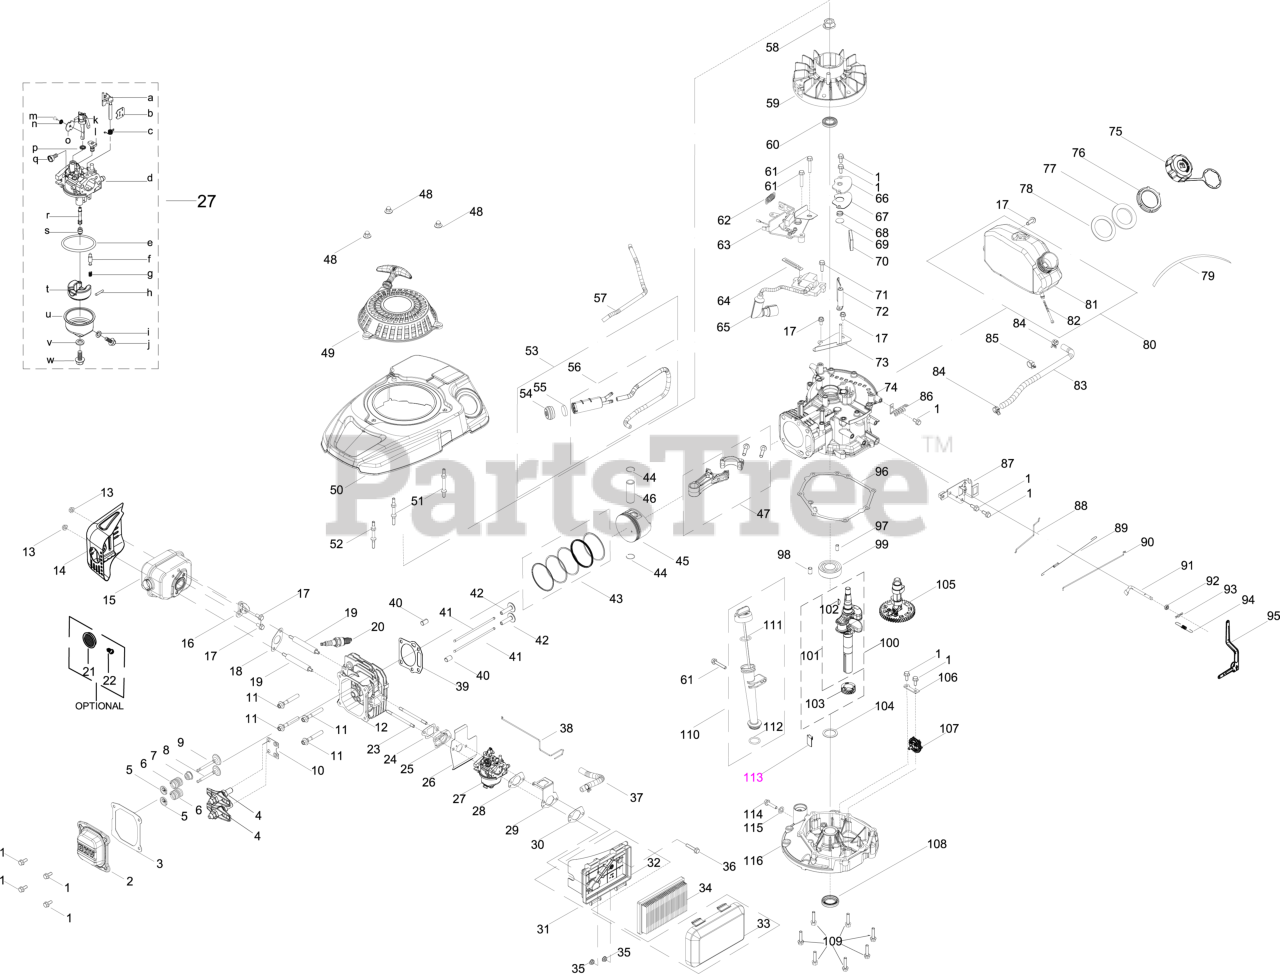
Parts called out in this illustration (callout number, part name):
1	BOLT M6-1 x 14 GR8.8
2	VALVE COVER
3	VALVE COVER GASKET
5	VALVE RETURN SPRING
6	VALVE SPRING
7	INTAKE VALVE SEAL
8	EXHAUST VALVE
9	INTAKE VALVE
10	PUSH ROD GUIDE
11	BOLT-M8 x 54
12	CYLINDER HEAD
14	MUFFLER SHIELD
15	MUFFLER ASSEMBLY
16	THERMOSTAT
17	BOLT M6-1 x 12 GR8.8
18	MUFFLER GASKET
19	STUD M6-1 x 95
20	SPARK PLUG (F5RTC/RN11YC4/BPR5ES)
20	Cub Cadet SPARK PLUG-F5RTC
20	Genuine Factory Parts SPARK PLUG (14437)
21	SPARK ARRESTOR
22	SCREW M3.5 x 9.5
23	CARBURETOR STUD-M6 x 87
24	CARBURETOR INSULATOR GASKET
25	CARBURETOR INSULATOR
26	CARBURETOR GASKET
27	CARBURETOR
28	AIR FILTER BRACKET GASKET
29	CHOKE TEMP CONTROL BRACKET
30	AIR FILTER BASE GASKET
31	AIR FILTER HOUSING ASSEMBLY
33	AIR FILTER COVER
36	BOLT-M6-1 x 30 GR8.8
37	BREATHER HOSE
38	CHOKE TEMP CONTROL LINKAGE
39	CYLINDER HEAD GASKET
40	PIN (10MMx16MM)
41	PUSH ROD
43	PISTON RING SET
44	WRIST PIN CLIP
47	CONNECTING ROD ASSEMBLY
48	ACORN NUT M6-1
49	RECOIL STARTER ASSEMBLY
50	BLOWER HOUSING
51	STARTER/SHROUD REAR STUD
52	STARTER/SHROUD FRONT STUD
54	CARBON CANISTER FILTER CAP
55	CARBON CANISTER FILTER
56	CARBON CANISTER
57	CARBON CANISTER PURGE HOSE
58	FLYWHEEL NUT M14-1.5
60	UPPER CRANKSHAFT SEAL
61	BOLT M6-1 x 35 GR8.8
62	ENGINE BRAKE SPRING
63	ENGINE BRAKE ASSEMBLY
64	FLEXIBLE CLAMP
65	IGNITION COIL
66	BREATHER COVER PLATE
67	BREATHER GASKET
68	BREATHER VALVE SPRING
69	BREATHER VALVE
70	BREATHER SCREEN
71	BOLT M6-1 x 20 GR8.8
73	AIR VANE BRACKET
75	FUEL CAP ASSEMBLY
76	FUEL TANK NUT
77	FUEL TANK GROMMET
78	FUEL TANK LOWER GROMMET
79	CABLE TIE 3x150
82	FUEL FILTER
84	CARBURETOR HOSE CLAMP
85	FUEL LINE SUPPORT CLAMP
86	FLEXIBLE CLAMP
87	COMPONENT BRACKET
88	CHOKE LINKAGE
89	THROTTLE LINKAGE SPRING
90	THROTTLE LINKAGE
91	GOVERNOR ARM SHAFT
94	GOVERNOR SPRING
95	GOVERNOR ARM ASSEMBLY
96	CRANKCASE COVER GASKET
97	DOWEL PIN 7 X 14
98	DOWEL PIN 9 X 14
100	CRANKSHAFT ASSEMBLY
101	CRANKSHAFT
102	WOODRUFF KEY
104	THRUST WASHER
105	CAMSHAFT
106	GOVERNOR GEAR MOUNTING PLATE
107	GOVERNOR GEAR/SHAFT ASSEMBLY
108	LOWER CRANKSHAFT SEAL
109	BOLT-M6-1 x 28 GR8.8
110	OIL DIPSTICK ASSEMBLY
113	OIL RETURN SEAL
114	OIL DRAIN PLUG
115	FLAT WASHER
116	CRANKCASE COVER
